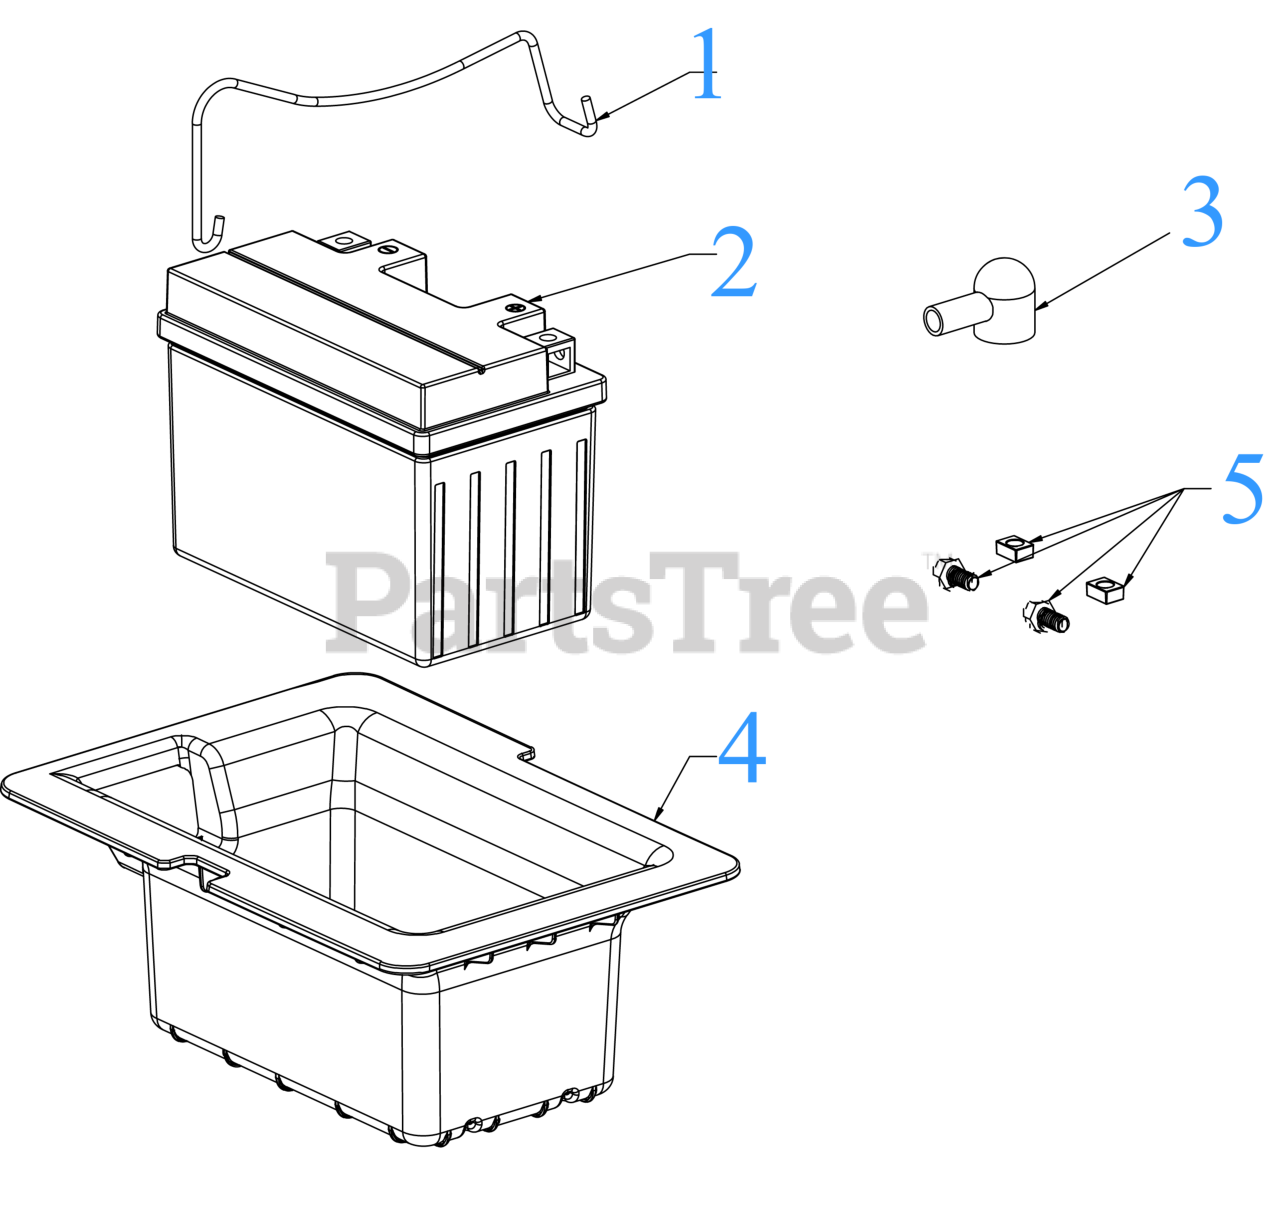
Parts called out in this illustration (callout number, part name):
1	BATTERY ROD ASSEMBLY (POWDER BLACK)
2	BATTERY (11AHR AGM 210CCA)
3	TERMINAL COVER RED
4	BATTERY TRAY
5	BATTERY HARDWARE KIT
